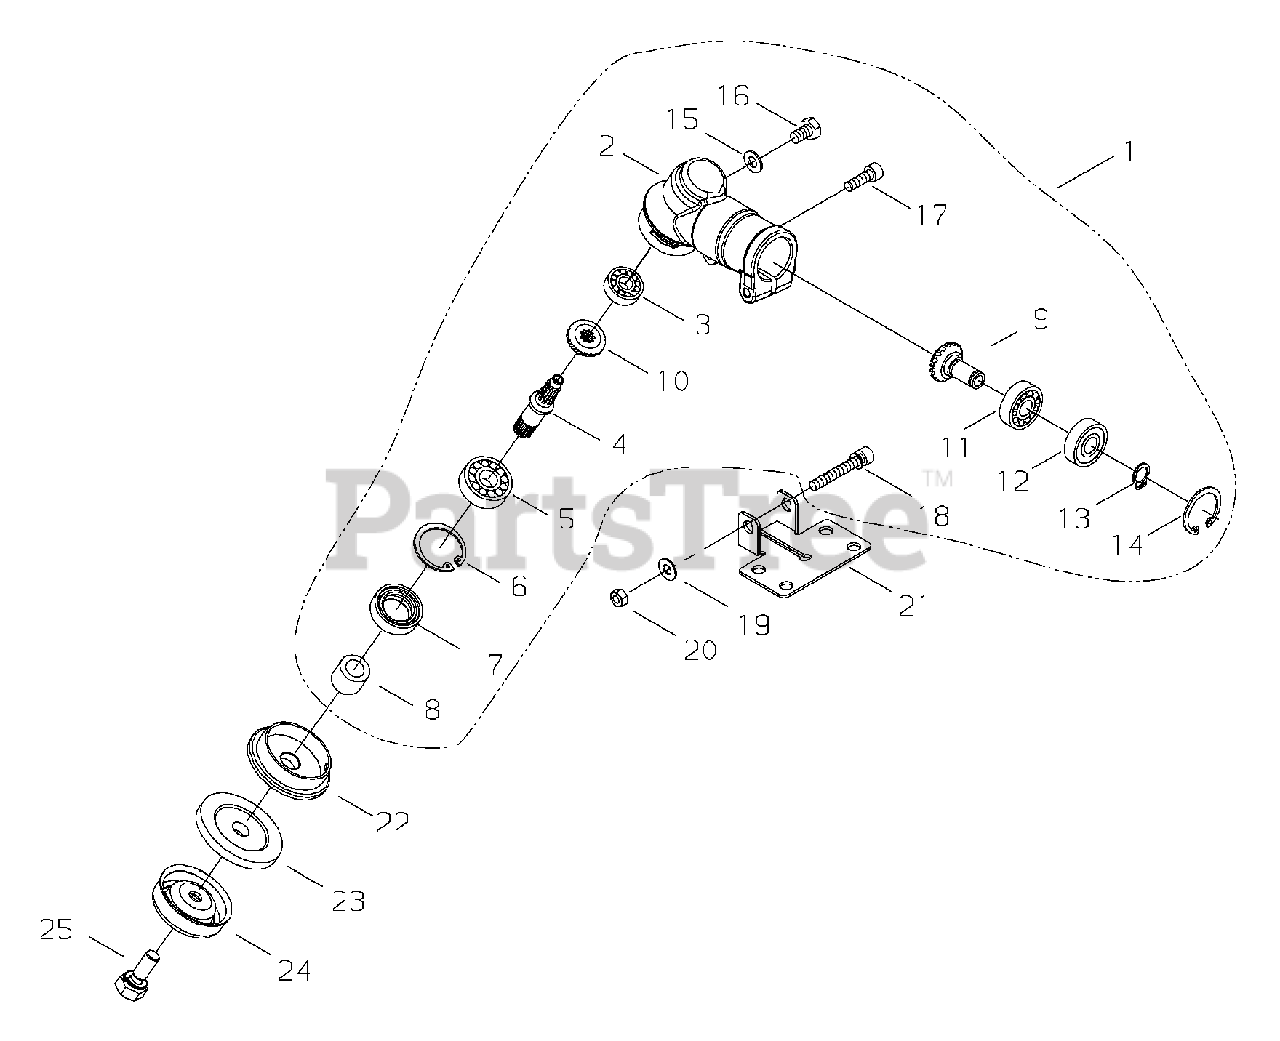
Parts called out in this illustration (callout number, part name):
1	GEAR CASE ASSY
2	CASE, GEAR
3	BEARING, BALL - 626MOS
4	GEAR - SHAFT
5	BEARING, BALL - 6000MOS
6	RING, RETAINING - 26
7	SEAL, OIL
8	COLLAR
9	GEAR - SHAFT
10	GEAR - BEVEL
11	BEARING, BALL - 609 MOS
12	BEARING, BALL - 609Z MOS
13	RING, RETAINING - 9
14	RING, RETAINING - 24
15	WASHER - 6
16	BOLT - 6X10
17	SCREW - 5X10
18	SCREW - 5X40
19	WASHER - 5
21	MOUNTING PLATE, SHIELD
22	HOLDER - A
23	CLIP
24	GUARD
25	SCREW - 7X20
